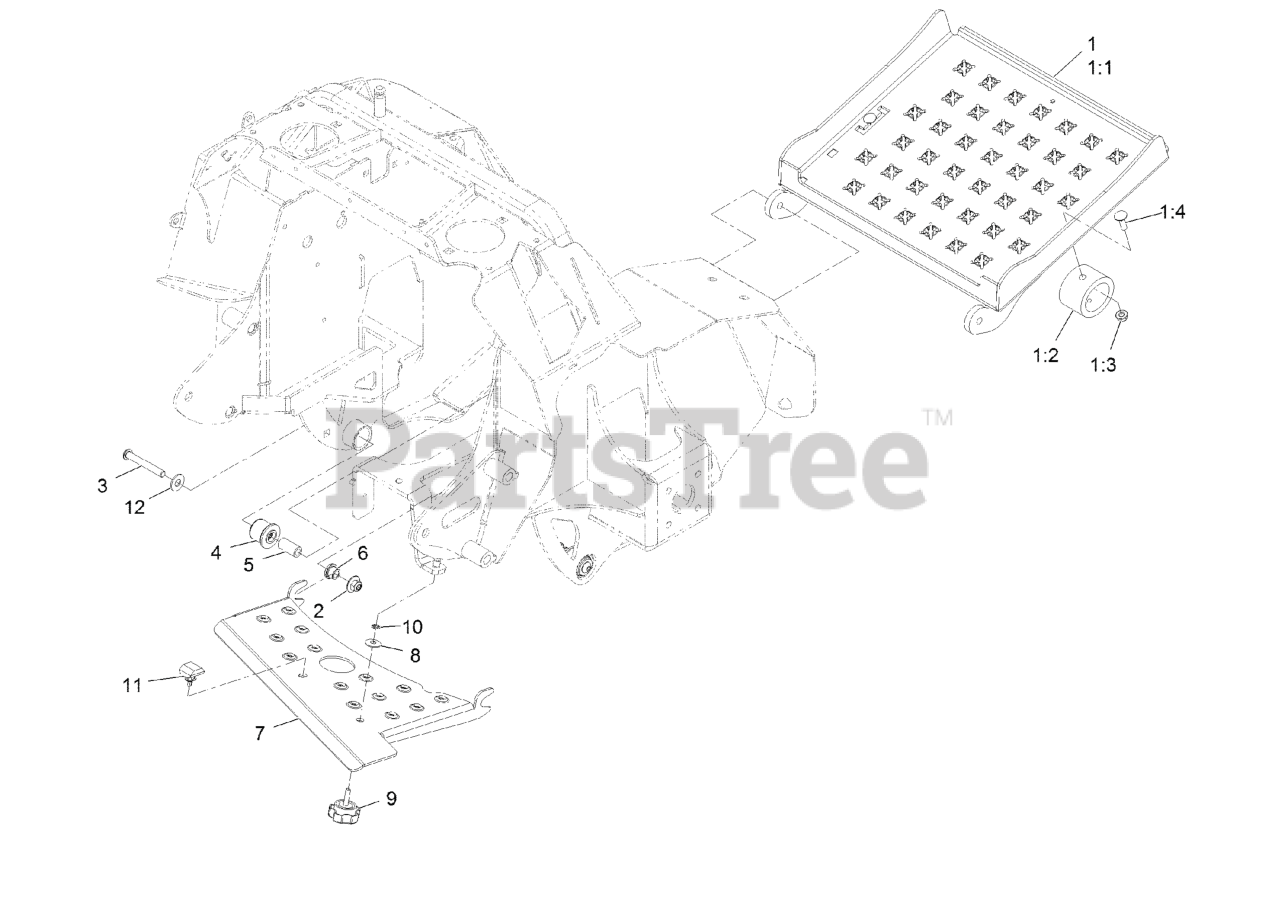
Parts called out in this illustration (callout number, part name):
1	Platform, ASM
1:1	Wld, Platform
1:2	BUMPER-ISOLATOR
1:3	NUT-HF, NI
1:4	BOLT-CARR
2	Nut-Nyloc 3/8-16 Flg
3	Screw-HSBH
4	BUSHING-RUBBER, SUSPENSION
6	BUSHING-FLANGED
7	Deflector-Air,36
8	WASHER-BELLEVILLE
10	NUT-RETAINING
11	BUMPER-ROPS
12	WASHER-FLAT
